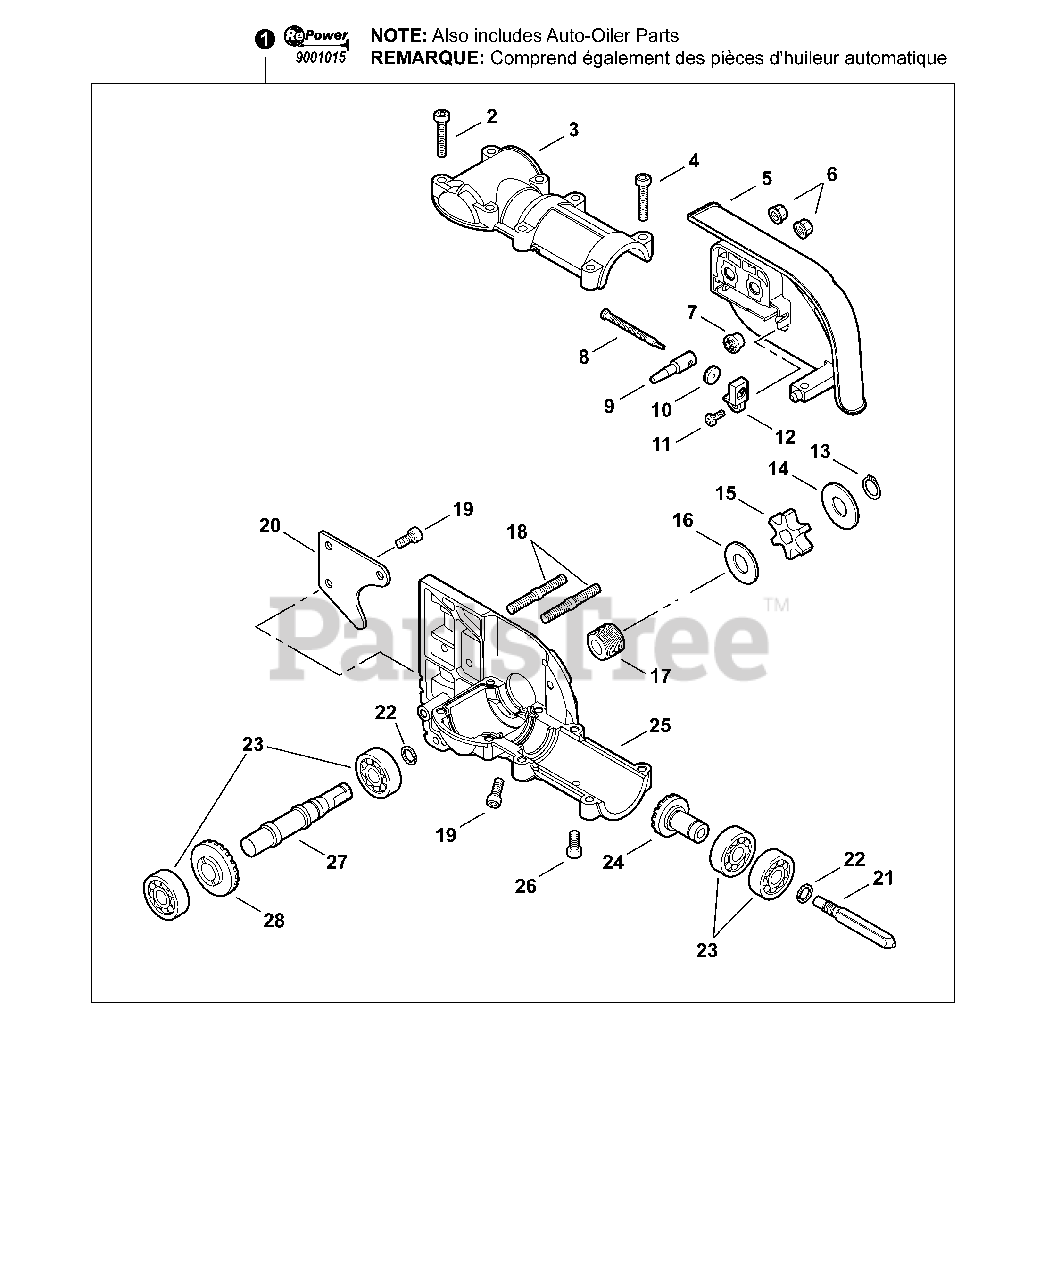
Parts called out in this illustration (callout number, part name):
1	CUTTING HEAD ASY
2	SCREW - 5×25
3	CASE, GEAR - UPPER
4	SCREW - 5×25
5	GUARD, SPROCKET
6	NUT - 6 -- FLANGE
7	GEAR - 14 TOOTH
8	SCREW, TENSIONER
9	TENSIONER, CHAIN
10	GEAR - 14 TOOTH
11	SCREW - 4×8
12	BRACKET, TENSIONER
13	RING, RETAINING
14	WASHER - 10
15	SPROCKET, DRIVE
17	GEAR, WORM
18	STUD, GUIDE BAR
19	SCREW - 5×10
21	CONNECTOR, SHAFT
22	RING, RETAINING - 12
23	BEARING, BALL - 6001
24	GEAR, BEVEL - 15 TOOTH
25	CASE, GEAR - LOWER
26	SCREW - 5×10
27	GEAR, SHAFT
28	GEAR, BEVEL - 23 TOOTH
